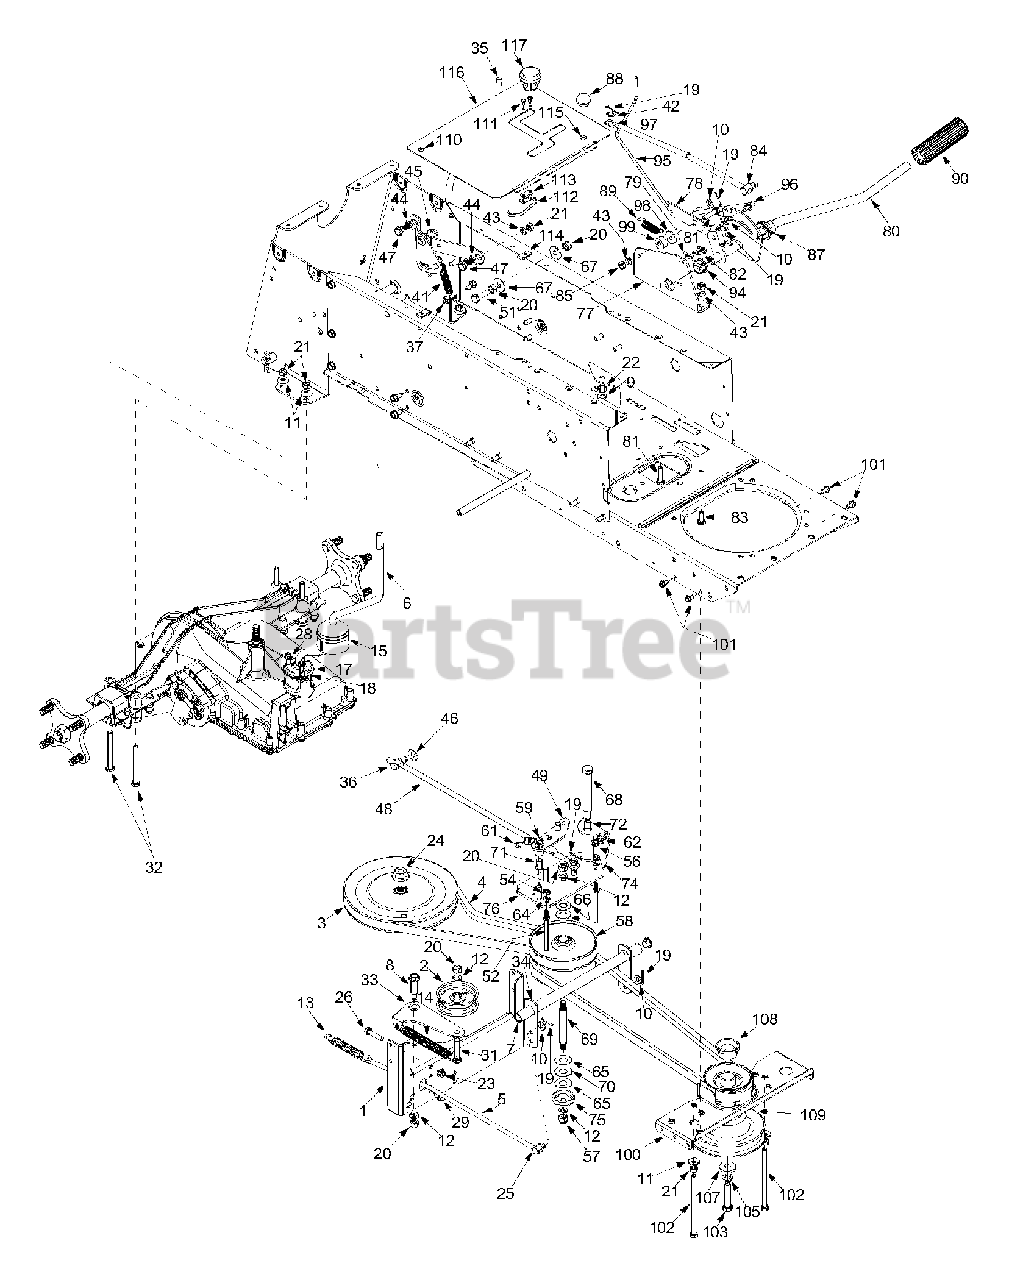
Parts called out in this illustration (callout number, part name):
3	Pulley: V Type
4	V Belt
5	Brake Rod
6	Shift Lever
7	Flange Bearing
8	Shoulder Screw
9	Lock Washer
10	Flat Washer
11	Bell Washer
12	Lock Washer
13	Extension Spring
14	Extension Spring
15	Boot: Shft.
17	Shift Cover
18	Insert: Shifter
19	Cotter Pin
20	Hex Nut 3/8-16
21	Hex Nut 5/16-18
22	Hex Nut 1/4-20
23	Flange Lock Nut 5/16-18
24	Flange Nut
25	Ferrule
26	Hex Screw 5/16-18 X 1.375"
28	Tt Screw 1/4-20 X 0.75"
29	Tt Screw 5/16-18 X 0.625"
31	Hex Screw 3/8-16 X 1.75"
32	Hex Screw 5/16-18 X 3.0"
36	Ferrule
37	Hex Lock Nut 5/16-18
41	Extension Spring
42	Flat Washer 3/8 X 0.620" X 0.033
43	Lock Washer
44	Spring Washer
45	Flat Washer
46	Flat Washer
47	Shoulder Screw
48	Link Rod: Speed Control
51	Hex Screw 3/8-16 X 1.25"
52	Belt Keeper
54	Hex Nut 1/4-20
56	Hex Nut 5/16-24
57	Hex Lock Nut 3/8-24
58	Drive Pulley: Variable Speed
59	Push Cap
61	Extension Spring
62	Lock Washer
65	Flat Washer 1.0" X 0.56"
66	Flat Washer 0.570" X 1.120" 0.062"
67	Bell Wash .396" X 1.140" X 0.095"
68	Shldr. Screw 3/8-24:0.625" X 3.50"
69	Shaft
70	Thrust Bearing
71	Flange Bearing
72	Flange Bearing
74	Support Bracket
75	Retainer Cup
82	Ab Screw
83	Hex Screw 5/16-18 X 0.75"
84	Ferrule
87	Hairpin Clip
89	Extension Spring
90	Foot Pad
94	Hex Flange Bearing
95	Pedal Lock Rod
96	Brake Link Rod
97	Speed Control Link
98	Shoulder Spacer
99	Spacer
102	Hex Screw 5/16-18 X 5.25"
103	Hex Screw 7/16-20 X 2.0"
105	Lock Washer 7/16
107	Flat Washer 0.450 x 1.250
108	Spacer
109	Engine Pulley
110	B Screw #10-16 x 0.5"
111	AB Screw #8-18 x 0.5"
112	Sw.:Spr.
113	Insulator Nut Plate
114	Speed Nut: U Type
115	Snap Bushing
